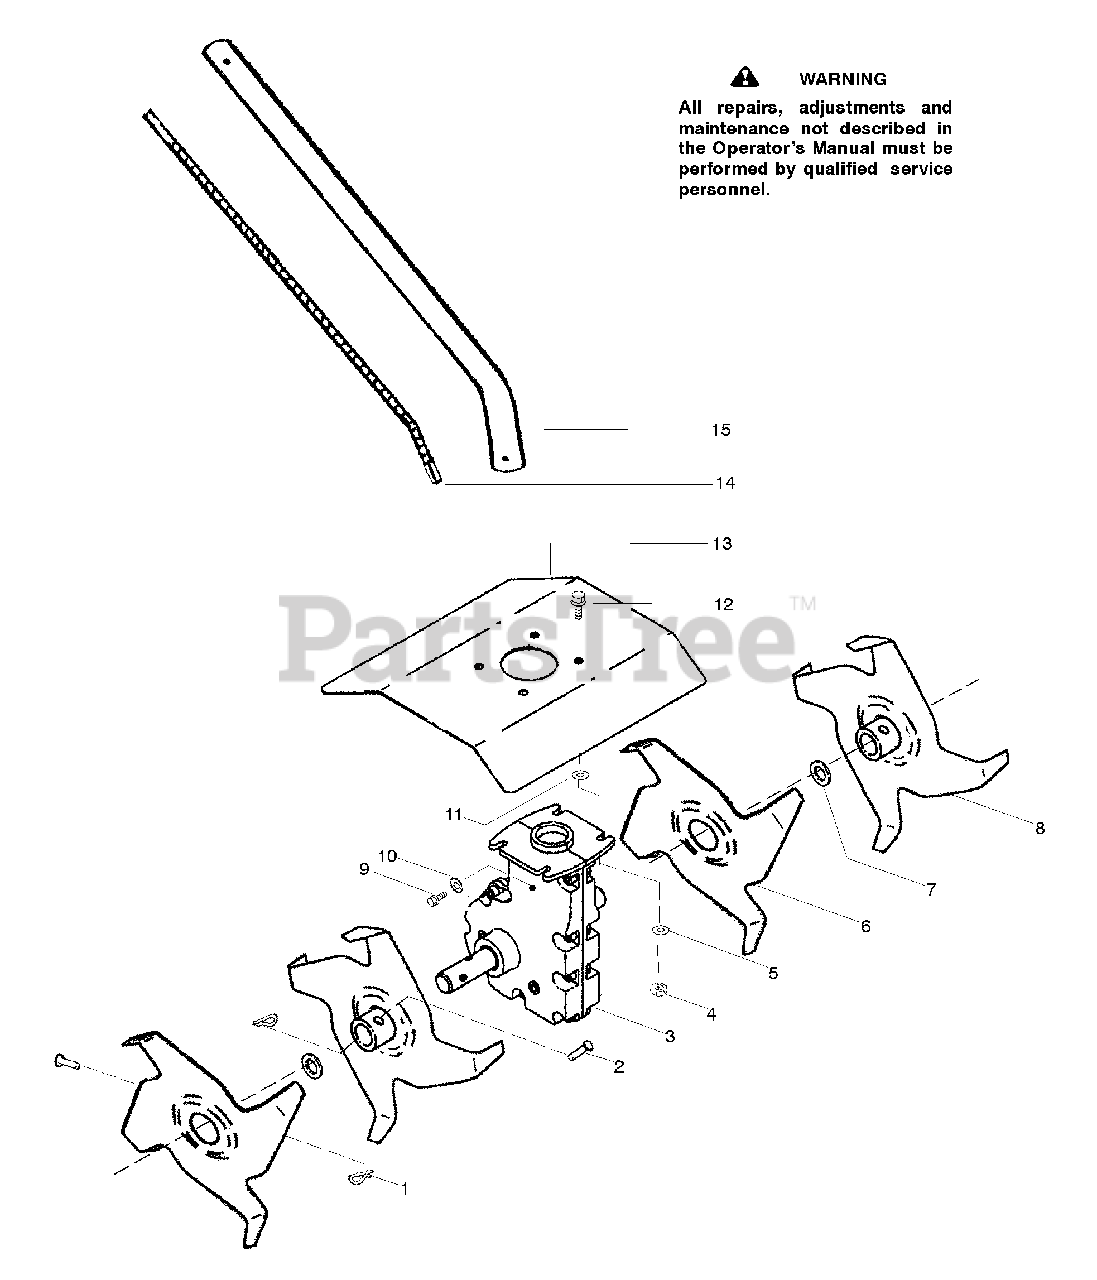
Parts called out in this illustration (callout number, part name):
1	Retainer-Hairpin
2	Pin-Clevis
3	Assy-Gearbox
5	Washer-Flat
6	Tine-Right Outside/Left Inside
7	Washer-Felt
8	Tine-Left Outside/Right Inside
9	Bolt-Hex
10	Washer-Lock
11	Washer-Flat
12	Bolt-Washer Head
13	Guard-blade
14	Shaft-Flex
15	Assy-Driveshaft
